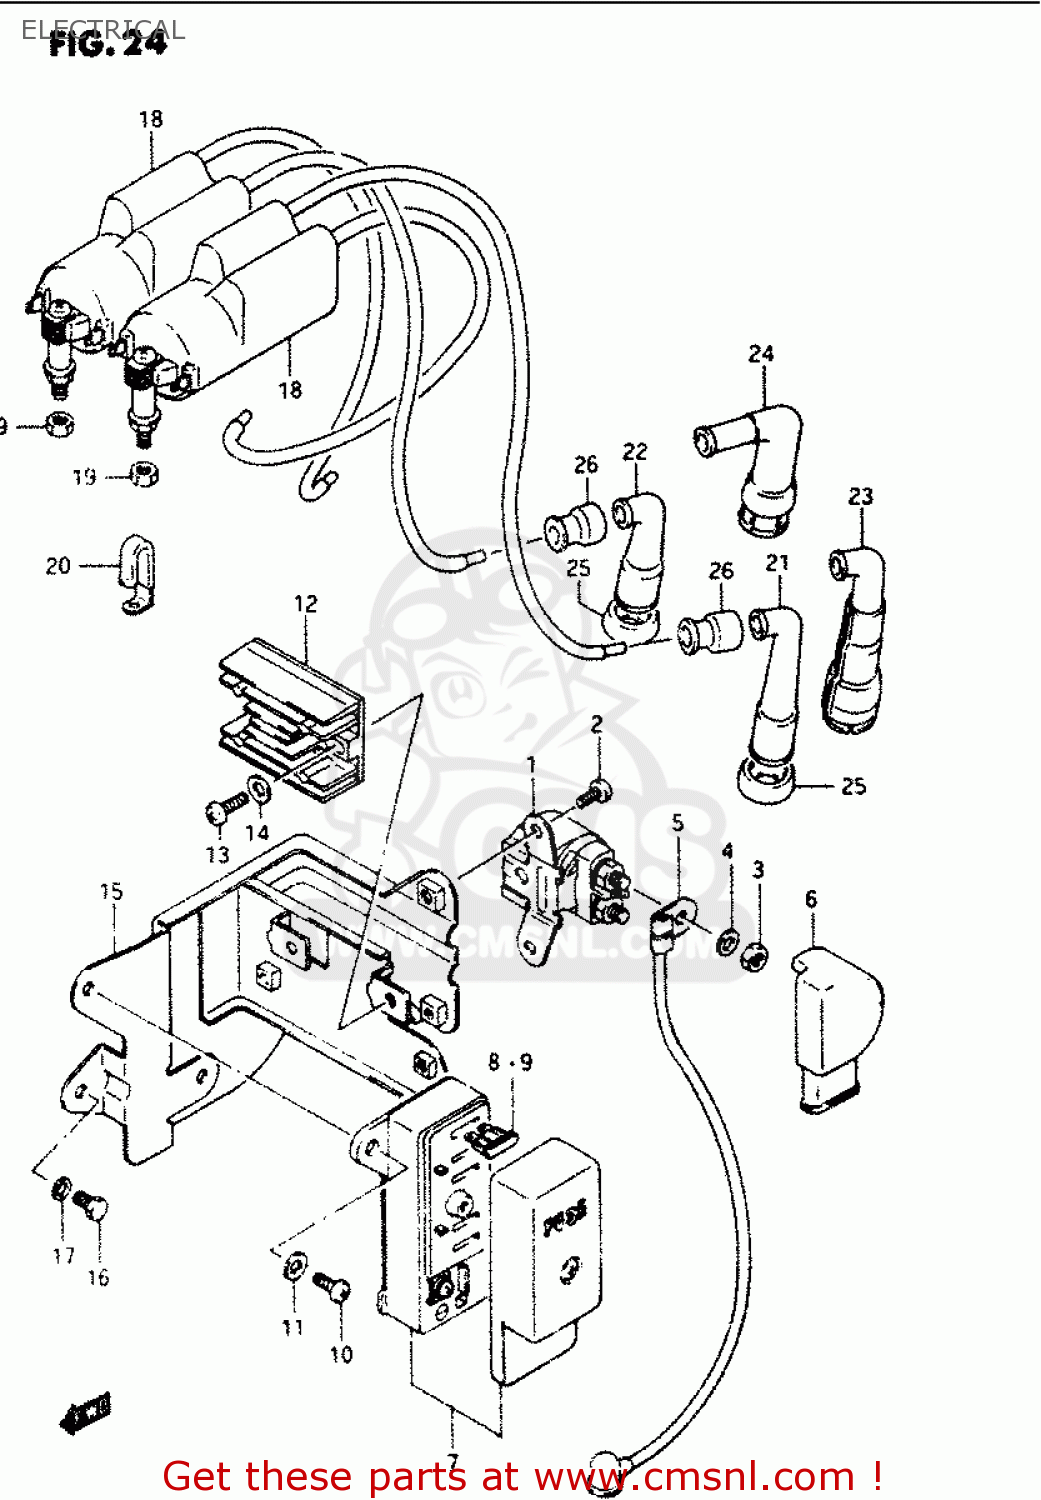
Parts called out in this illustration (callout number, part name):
1	RELAY ASSY,STARTING MOTOR
2	SCREW
3	NUT
4	WASHER,LOCK
5	WIRE,STARTER MOTOR LEAD
6	CAP,STARTER RELAY TERMINAL
7	BOX ASSEMBLY,FUSE
8	FUSE(10A)
9	FUSE(15A)
10	SCREW
11	WASHER, LOWER
12	RECTIFIER ASSEMBLY
13	SCREW
14	WASHER
15	HOLDER COMP,ELECTRONIC PARTS
16	BOLT
17	WASHER,LOCK
18	COIL ASSEMBLY,IGNITION
19	NUT
20	CLAMP
21	CAP ASSY,SPARK PLUG
22	CAP,SPARK PLUG
23	CAP,SPARK PLUG
24	CAP, SPARK PLUG (S)
25	SEAL,SPARK PLUG
26	SEAL,SPARK PLU
